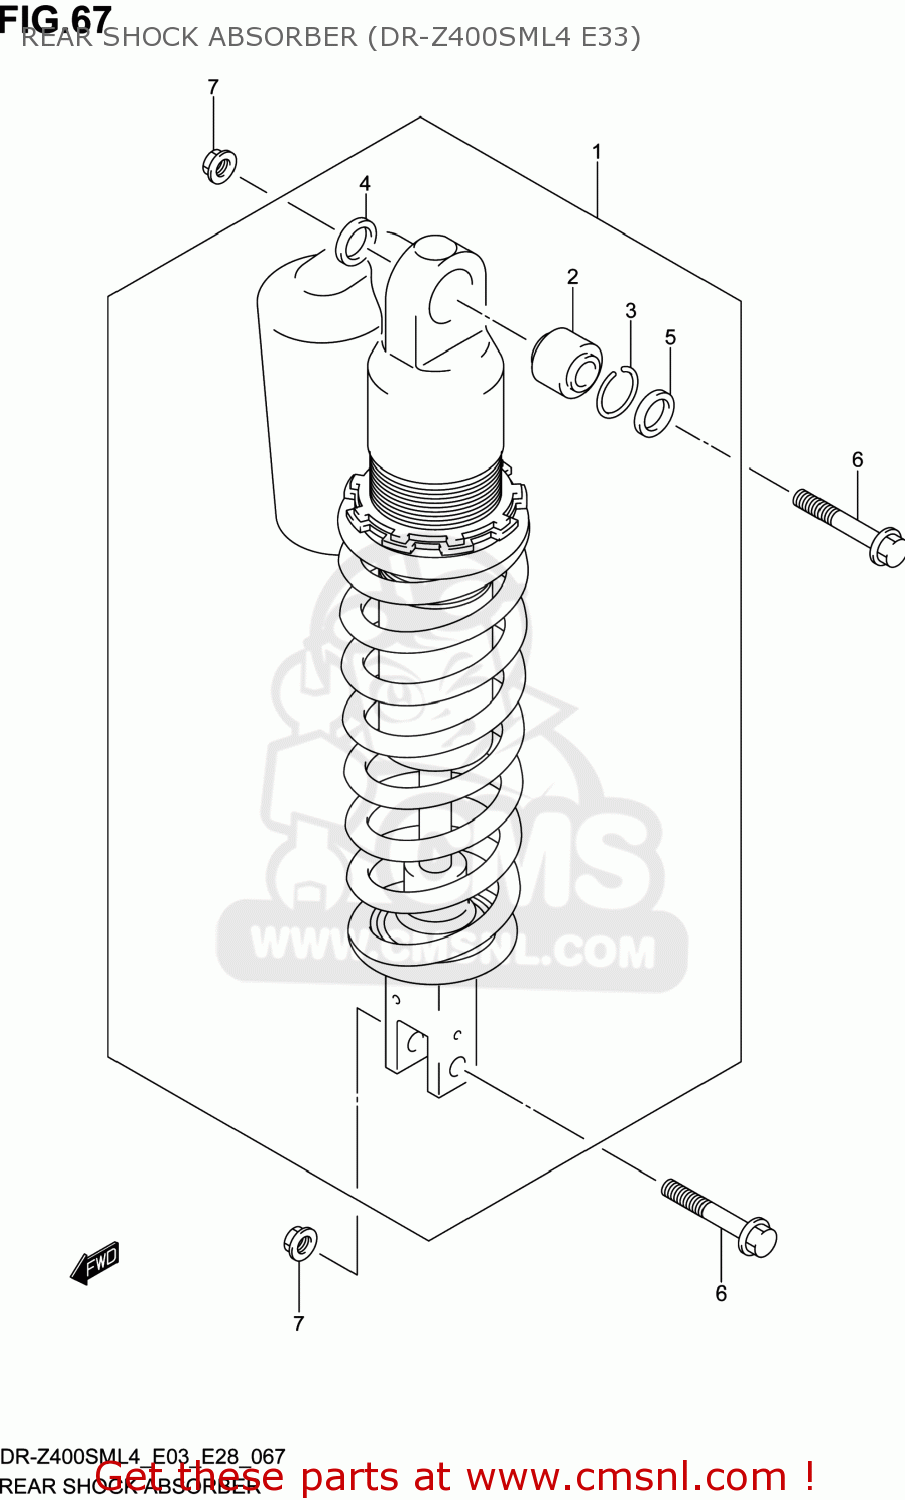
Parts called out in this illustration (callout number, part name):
1	ABSORBER ASSY,REAR SHOCK
2	BEARING,RR SHOCK ABSORBER
3	RING,STOPPER
4	SEAL,DUST UPR,R
5	SEAL,DUST UPR,L
6	BOLT(10X47.5)
7	NUT
